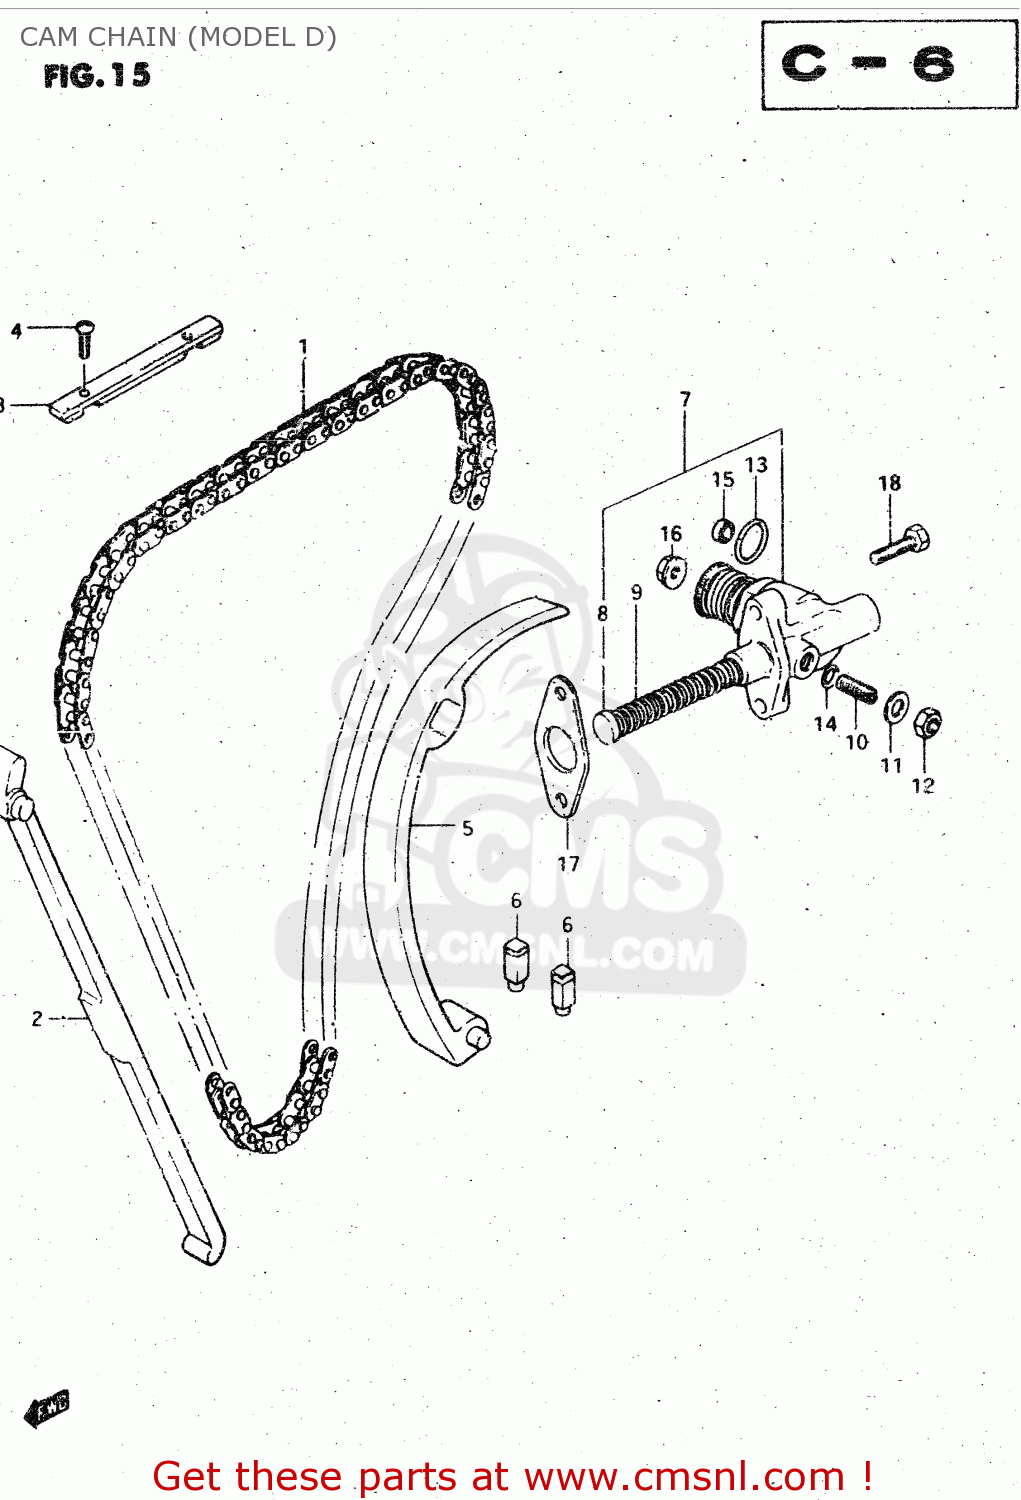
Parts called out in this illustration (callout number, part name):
1	CHAIN,CAMSHAFT DRIVE
2	GUIDE,CAM CHAIN NO.1
3	GUIDE,CAM CHAIN NO.3
4	SCREW 5X12
5	TENSIONER,CAM CHAIN
6	CUSHION,CAM CHAIN TENSIONER
7	ADJUSTER ASSEMBLY,TENSIONER
8	ROD,PUSH
9	SPRING
10	SCREW,TENSIONER ADJUST
11	WASHER,8.5X16X
12	NUT
13	O RING(D:2.4,ID:20.8)
14	O RING(D:1.9,ID:5.7)
15	SEAL,OIL(10X16X4)
16	NUT
17	GASKET,TENSIONER ADJUSTER (MCA)
18	SCREW
